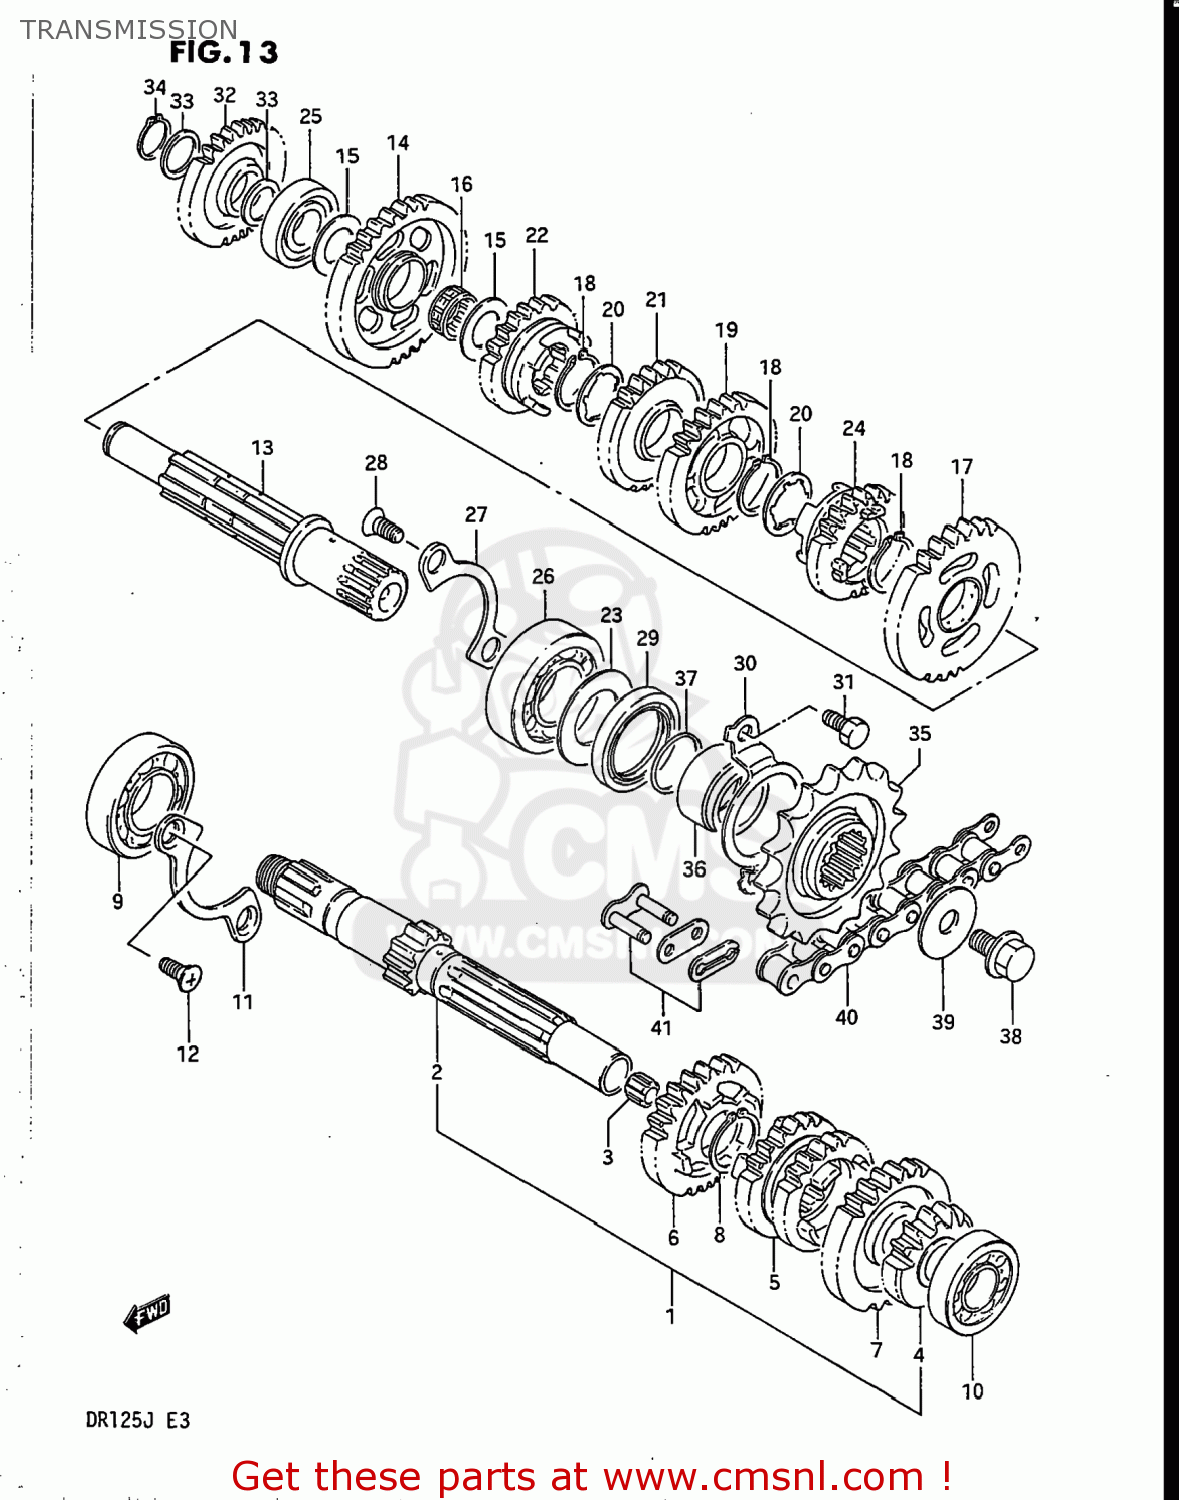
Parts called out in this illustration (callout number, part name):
1	SHAFT ASSEMBLY,COUNTER
2	SHAFT,COUNTER
3	BUSH
4	GEAR,SECOND DRIVE
5	GEAR,THIRD & FOURTH DRIVE,N
6	GEAR,FIFTH DRIVE
7	GEAR,SIXTH DRIVE
8	CIRCLIP
9	BEARING
10	BEARING, LH
11	RETAINER,DRIVE SHAFT BEARING
12	SCREW
13	SHAFT,DRIVE
14	GEAR,FIRST DRIVEN
15	WASHER
16	BEARING(15X19X7.8)
17	GEAR,SECOND DRIVEN
18	CIRCLIP
19	GEAR,THIRD DRIVEN
20	WASHER,LOCK
21	GEAR,FOURTH DRIVEN
22	GEAR,FIFTH DRIVEN
23	WASHER,OIL SEALING
24	GEAR,SIXTH DRIVEN
25	BEARING(15X36X12)
26	BEARING(22X50X14)
27	RETAINER,DRIVE SHAFT BEARING
28	SCREW
29	SEAL,OIL(30X40X6)
30	RETAINER,DRIVESHAFT O
31	BOLT
32	GEAR,KICK STARTER IDLE(NT:26)
33	WASHER
34	CIRCLIP,15MM
35	SPROCKET,ENGINE
36	SPACER,ENGINE SPROCKET
37	O RING(D:2.5,ID:21)
38	BOLT
39	WASHER
40	CHAIN ASSEMBLY,DRIVE
41	JOINT SET,CHAIN
